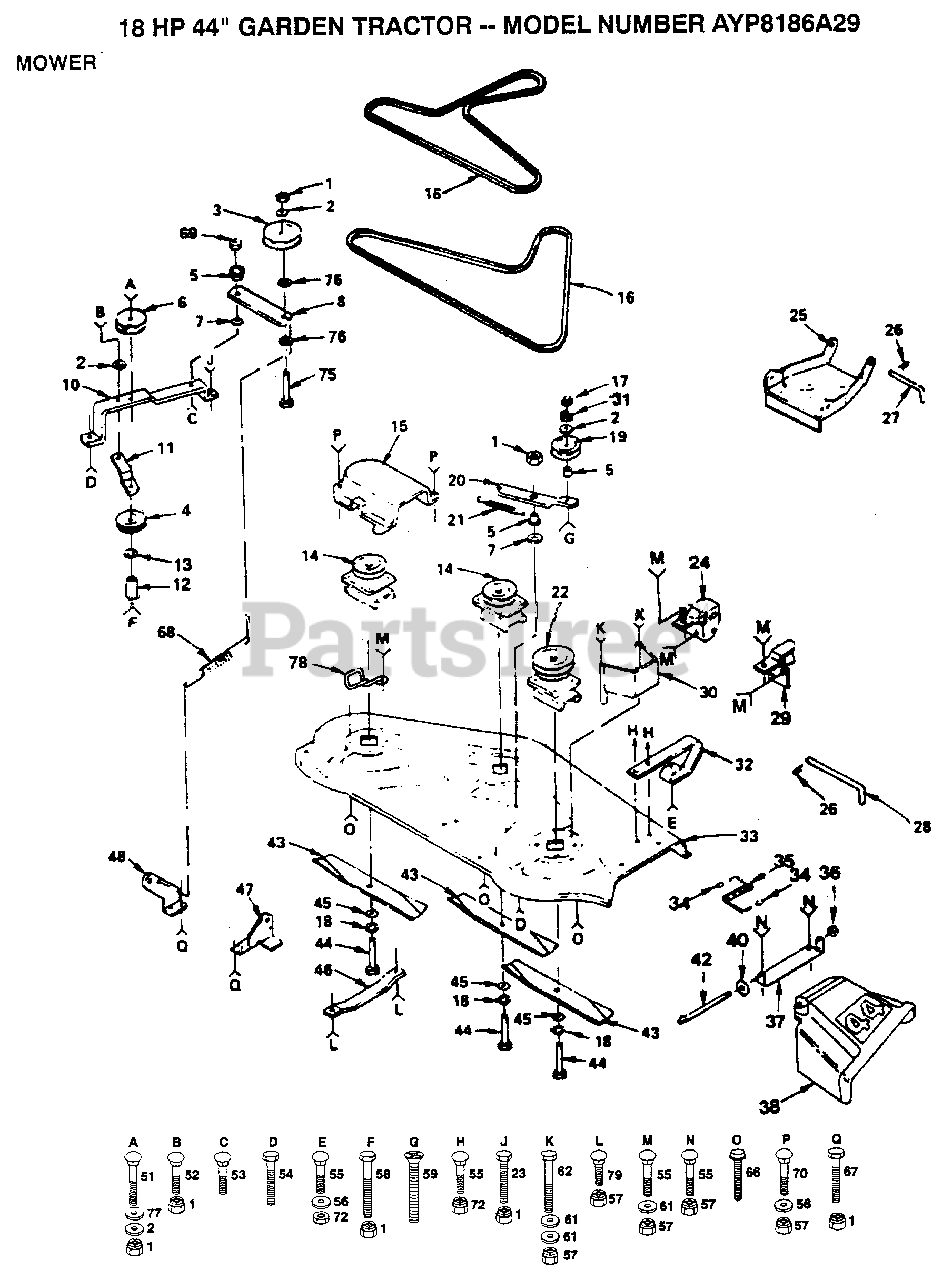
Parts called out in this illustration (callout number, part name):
2	WASHER
3	PULLEY IDLER
4	IDLER-FLAT T
5	SPACER RETAINER
6	IDLER-INSIDE T
7	"WASHER, WEAR LT"
8	ARM IDLER
10	"SUPPORT YT, BAR"
11	BRACE-IDLER YT
12	SPACER
13	WASHER
15	GUARD YT
16	BELT-V.79.1.MWR
17	NUT.HEX.3/8-16UNC
19	IDLER.FLAT.GTV
20	ARM-IDLER YT
23	BOLT
24	BRACKET LH YT
25	"STOP, LINK PARAL"
26	SPRING.RETAINER
27	"ROD, FRT. PARAL T"
28	HINGE PIN T
29	BRACKET RH YT
30	GUARD BELT HYT
31	LOCKWASHER
34	CAP-SLEEVE LT
36	NUT PUSH M
38	DEFLECTOR SHIELD
40	WASHER
42	ROD-HINGE T
44	BOLT.3/8-24X1-1/2
45	WASHER
46	RUNNER-LH M
47	BRKT SUSP REAR RH
48	BRKT SUSP REAR LH
51	BOLT
53	BOLT
55	BOLT
56	WASHER
58	BOLT - HEX 3/8 - 16 X 3
59	SCREW YT
61	WASHER M
62	BOLT
66	SCREW
67	BOLT
68	"SPRING.EXT.8.5"""
69	LOCKNUT
75	BOLT
76	WASHER
77	WASHER
78	BELT RETIANER
79	BOLT
